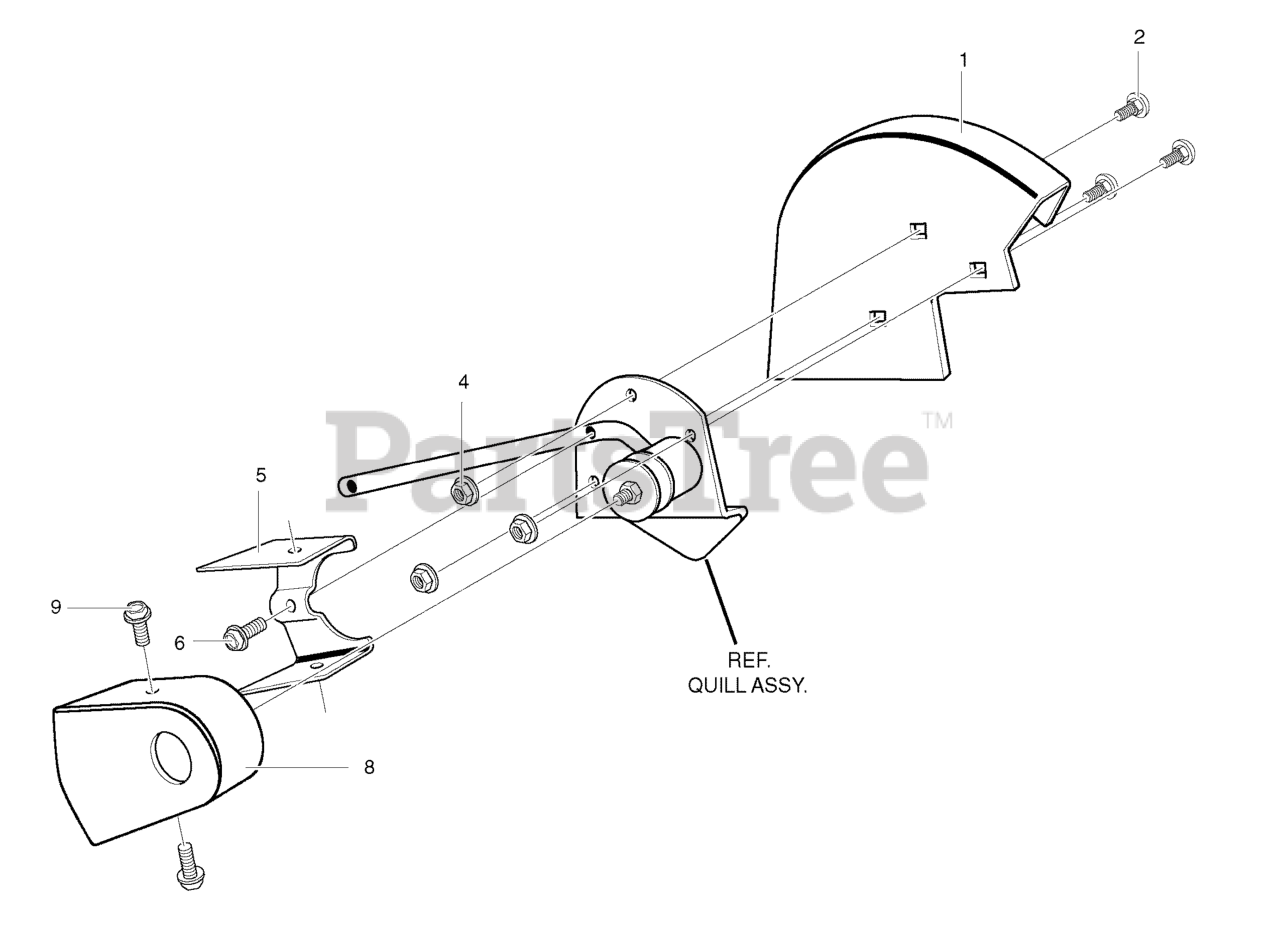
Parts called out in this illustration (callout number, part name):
1	GUARD, Blade
2	BOLT, Carriage 5/16-18x.63
4	NUT, 5/16-18
5	GUIDE, Belt Front
6	SCREW, 1/4-20x.50
8	COVER, Quill Pulley
9	SCREW, 10-16x.50
